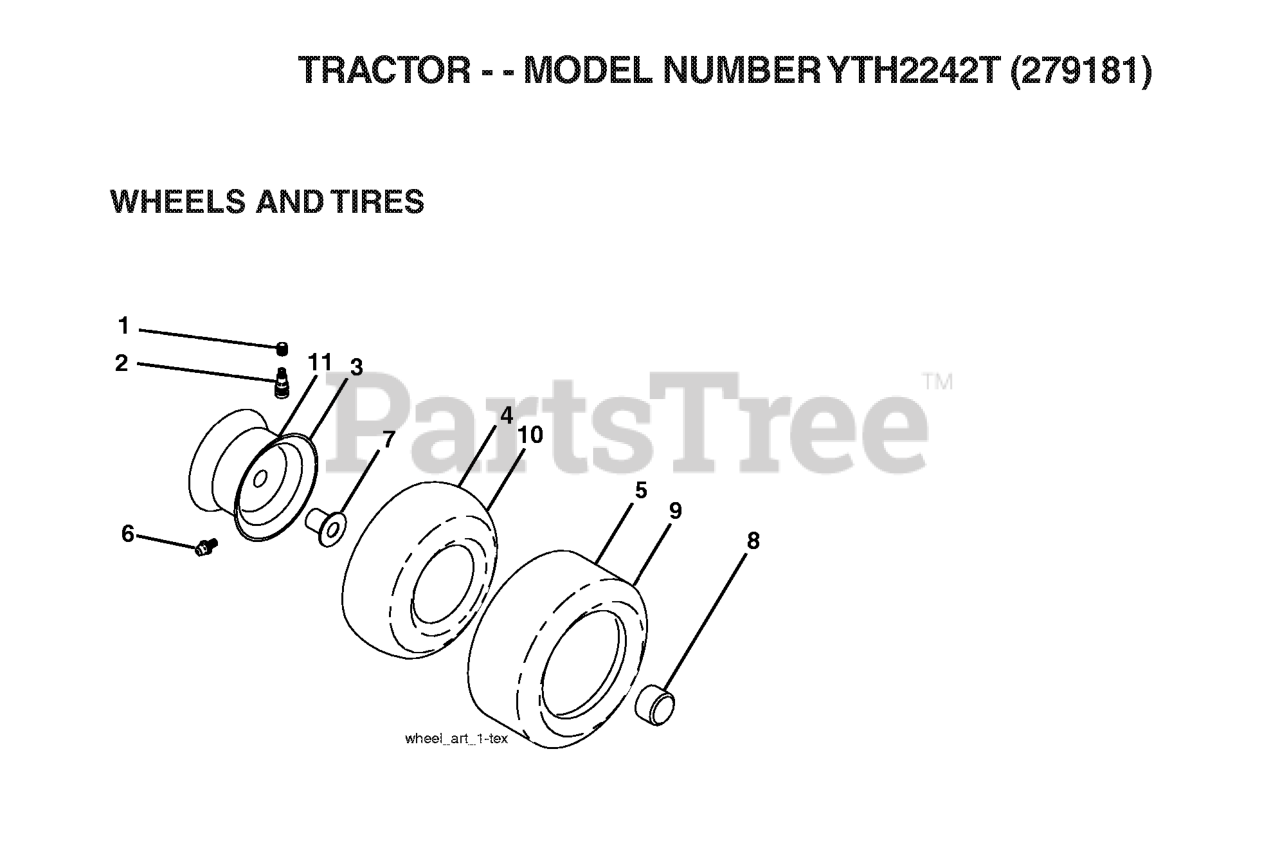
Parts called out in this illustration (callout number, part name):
2	VALVE STEM LT
3	RIM ASM 6" FRONT SILVER
4	TUBE.5.3/4.5/6
5	TIRE HEAVY DUTY
6	FITTING LT
7	BEARING T
8	CAP, AXLE BLK
9	TIRE.20X8-8.TURF.SAVER
10	TUBE
11	RIM ASM 8" REAR SILVER
